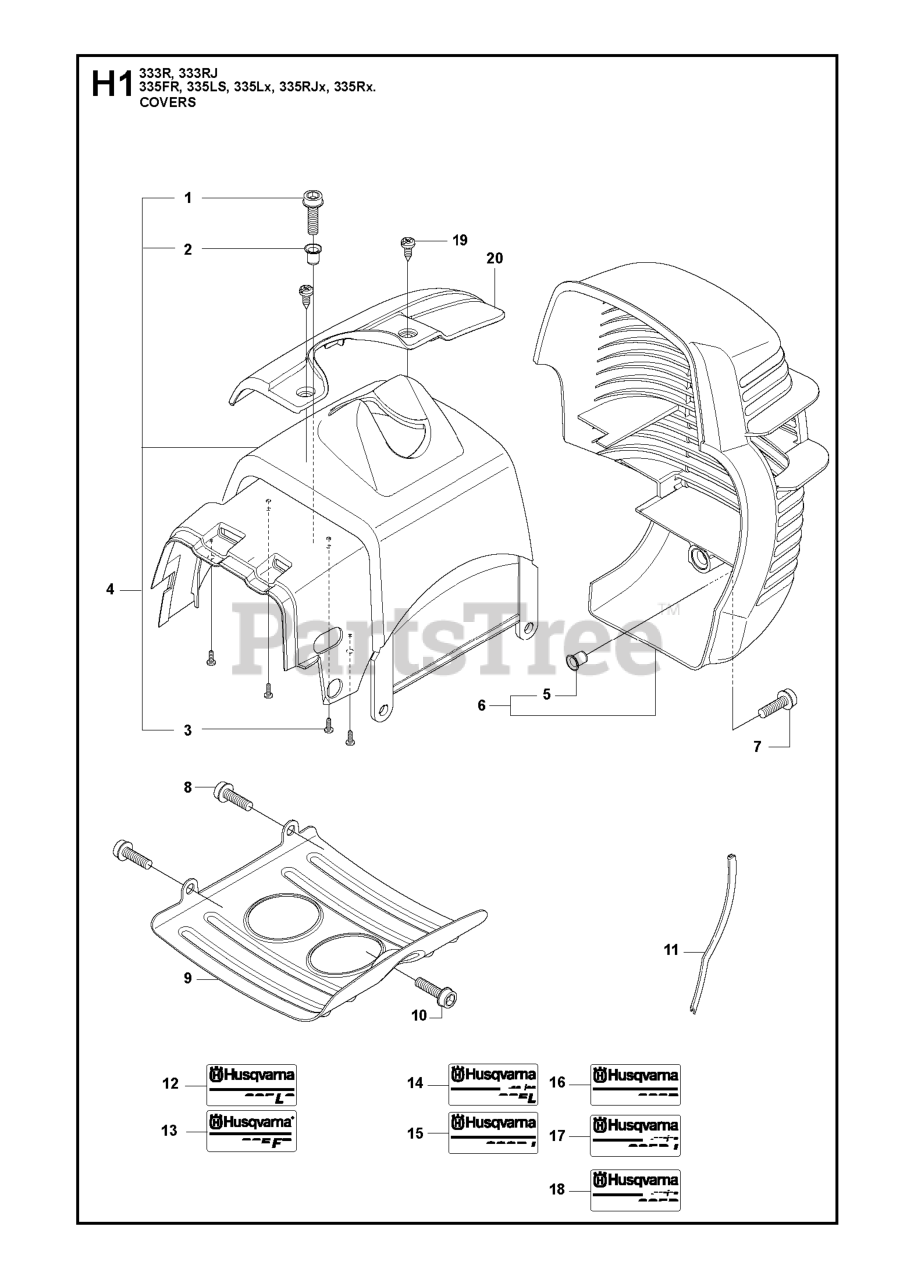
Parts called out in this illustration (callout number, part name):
4	RP CYLINDER COVER
6	PROTECTOR
12	DECAL
13	LABEL
14	DECAL CYLINDER COVER
15	DECAL CYLINDER COVER
16	DECAL
17	DECAL CYLINDER COVER
18	DECAL CYLINDER COVER
19	SCREW CCRPANT ST4.2X9.5 DS
20	ARM PROTECTION
